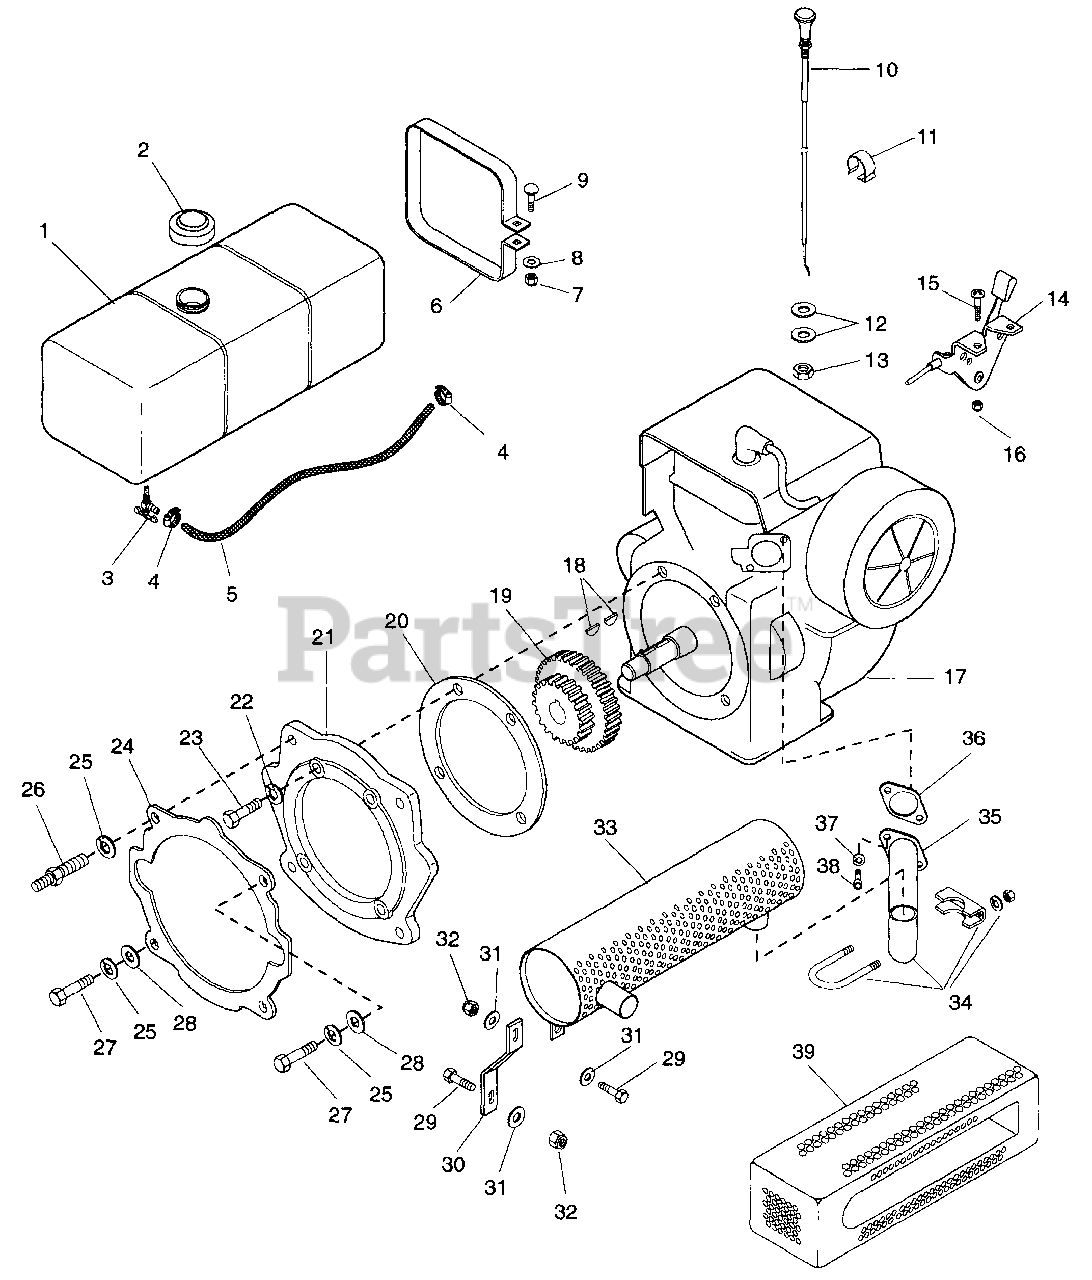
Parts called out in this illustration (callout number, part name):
1	Assembly, Fuel Tank
2	Cap, Gas Tank
3	Valve and Strainer
4	Hose Clamp
5	Gas Line - Bulk
6	Strap, Fuel Tank
7	Nut, Locking-Nylon .250-20
8	Washer-Flat-Steel .281 x .62 x .065
9	Bolt-Round Head Square Neck .25-20 x 1.75
10	Lever, Choke Control
11	Clamp
12	Washer-Flat-Steel .406 x .812 x .065
13	Nut-Jam .375-24
14	Lever, Throttle Control
15	Screw-Socket Head .31-18 x .75
16	Nut-Locking 10-24
17	Engine,12 HP Elect Magnum
18	Key, Woodruff .16 x .63
19	Gear, 10/12 DP 21/30 Teeth
20	Gasket, Engine to Adapter
21	Adapter, Engine
22	Washer-Lock .375 x .155
23	Bolt-Hex .38-16 x 1.00
24	Gasket, Chassis to Adapter
25	Washer-Lock .438 x .133
26	Stud
27	Bolt-Hex .44-14 x 1.50
28	Washer-Flat-Steel .469 x .938 x .065
29	Bolt-Hex .25-20 x .75 Grade 5
30	Brace, Muffler
31	Washer-Flat-Steel .312 x .734 x .065
32	Nut-Hex .250-20
33	Muffler
34	Clamp-Muffler 1.25
35	Header, Exhaust
36	Gasket, Exhaust
37	Washer-Lock .313 x .078
38	Screw-Cap .31-18 x .75
39	Guard, Muffler
